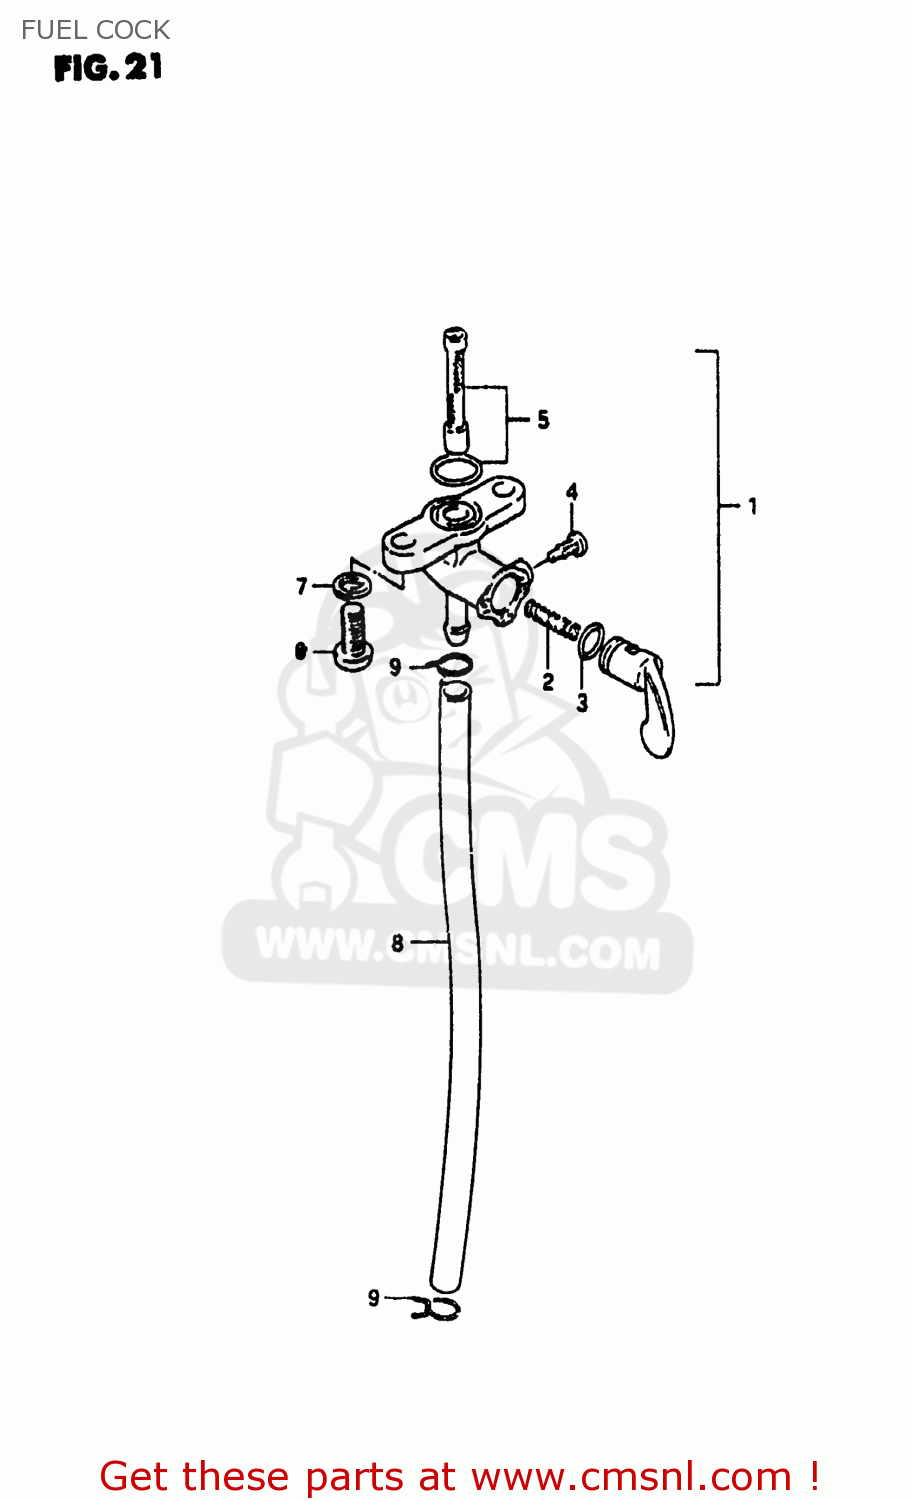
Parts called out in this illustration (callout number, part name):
1	COCK ASSEMBLY,FUEL
2	SPRING,FUEL COCK VALUE
3	O RING,LEVER
4	SCREW
5	FILTER SET FUEL
6	SCREW
7	LOCK WASHER
8	HOSE
9	CLAMP
